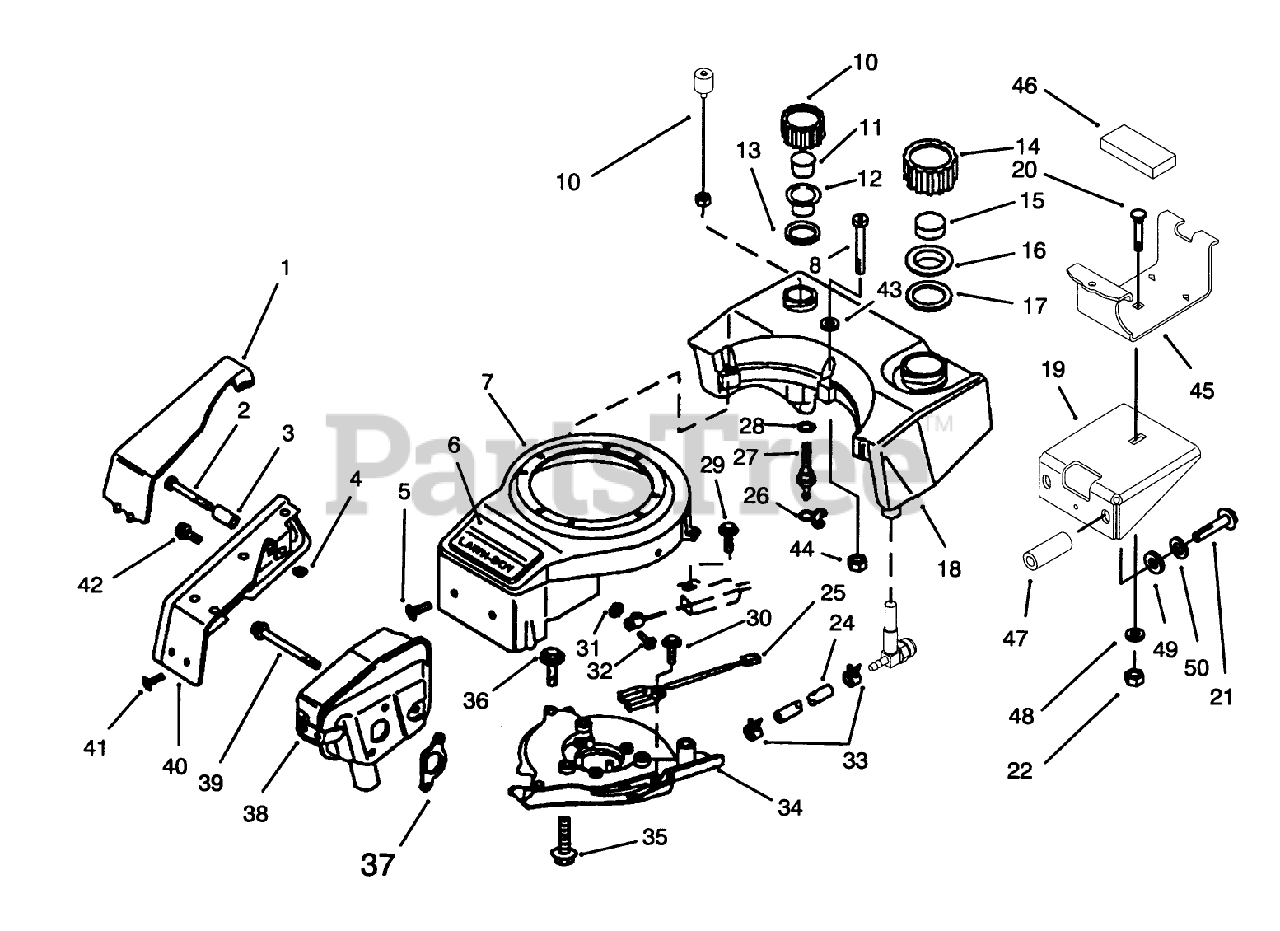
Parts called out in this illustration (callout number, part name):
1	COVER MUFFLER CP
2	SCREW SM
3	SPACER S
4	NUT-PUSH
6	APPLIQUE SM
8	SCREW-PPH
9	SWITCH AY-OIL S
10	CAP AY. OIL M
14	CAP AY - FUEL M
15	BAFFLE - FOAM SM
16	COVER-FUEL CAP F
17	GASKET-FUELCAP SM
20	SCREW-CARR
21	SCREW-HSH
22	NUT-HEX
23	DISC/LB SER.BUL.#6
24	GAS LINE SM
28	O-RING SM
29	SCREW-HH
31	NUT-LOCK, NI
33	HOSE CLAMP SM
35	SCREW-SEMS F
37	GASKET - EXH SM
39	SCREW-SEMS
40	MUFFLER GUARD AY
41	SCREW SM
42	SCREW S
43	WASHER-FLAT
44	NUT-LOCK, NI
45	STRAP,FUELTANK SM
47	SPACER SM
48	WASHER-FLAT
49	WASHER-FLAT
